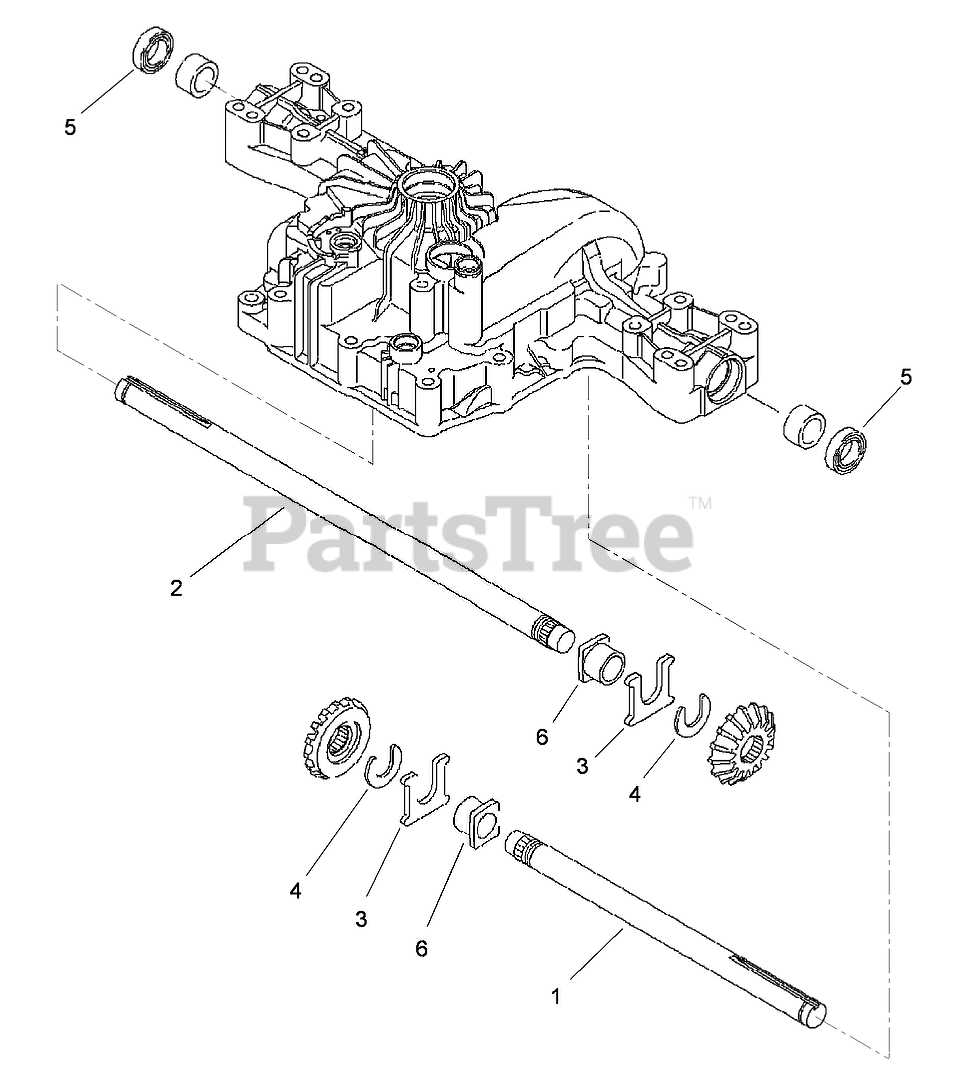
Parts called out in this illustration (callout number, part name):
1	Shaft-Axle, RH
2	Shaft-Axle, LH
3	Washer-Thrust
6	Bushing
